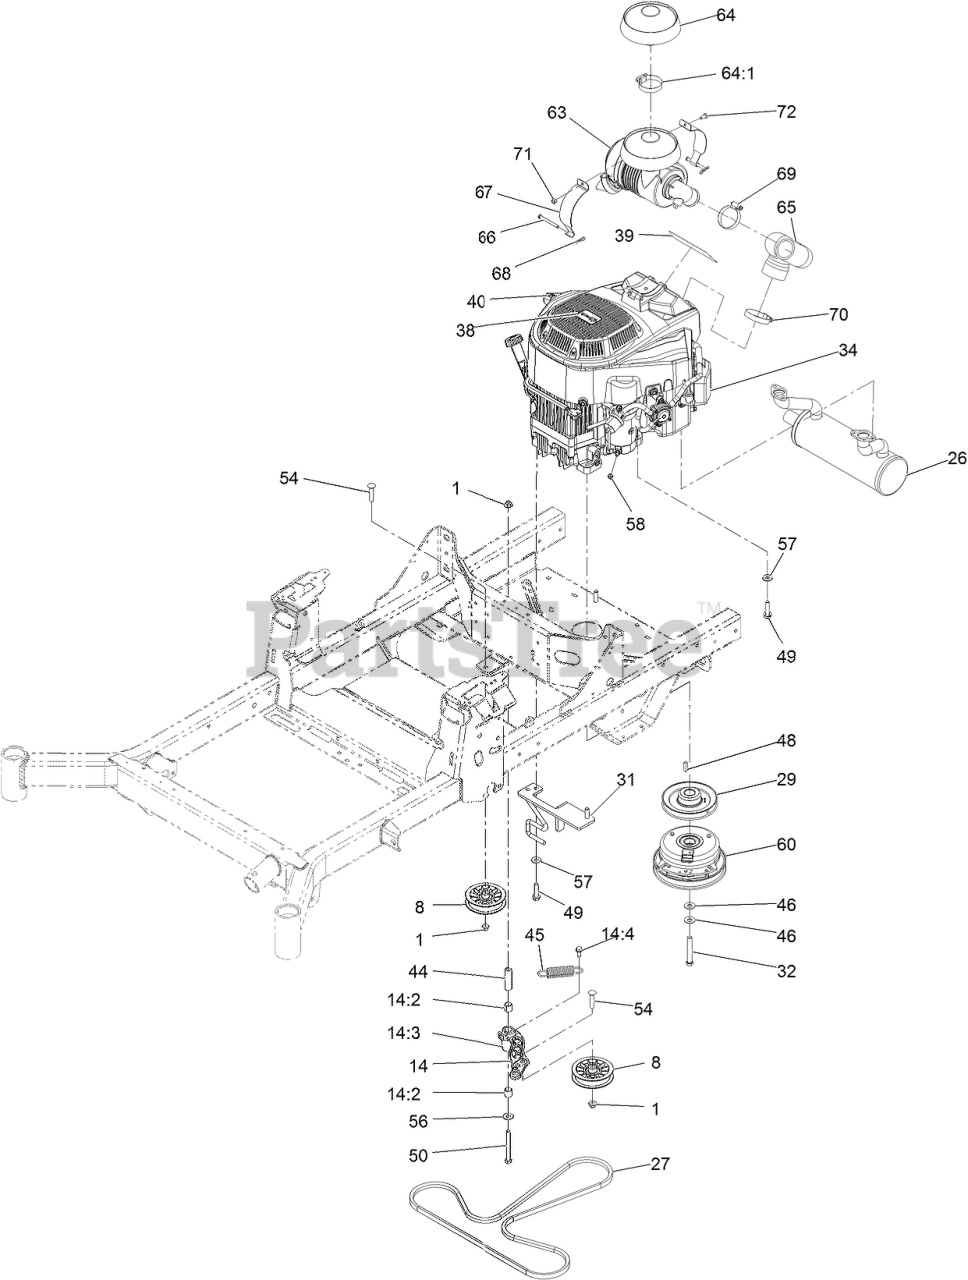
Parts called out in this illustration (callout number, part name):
1	NUT-HF, NI
8	PULLEY-FLAT IDLER
14	IDLER ARM ASM
14:2	SLEEVE-BEARING
14:3	FITTING-GREASE, 90 DEG
14:4	SCREW-THD ROLL, HWH
26	MUFFLER
27	BELT-V
29	SHEAVE-ENGINE
31	ANCHOR-CLUTCH
32	SCREW-HH W/LOCTITE
34	ENGINE-2P77F-HD
40	DECAL-DRAIN, OIL
44	BUSHING-PIVOT, IDLER
45	SPRING-EXTENSION
46	WASHER-SPRING
49	SCREW-HWH
50	SCREW-HH
54	SCREW-CARR
56	WASHER-FLAT
57	WASHER-BELLEVILLE
60	CLUTCH - 1.00 HD
63	AIR CLEANER ASM
64	RAIN CAP KIT
64:1	CLAMP-HOSE
65	HOSE-INTAKE
66	PIN-CLEVIS
67	STRAP-CANISTER, AIR
68	PIN-COTTER
69	CLAMP-HOSE
70	CLAMP-HOSE
71	NUT-HEX
72	SCREW-HH
